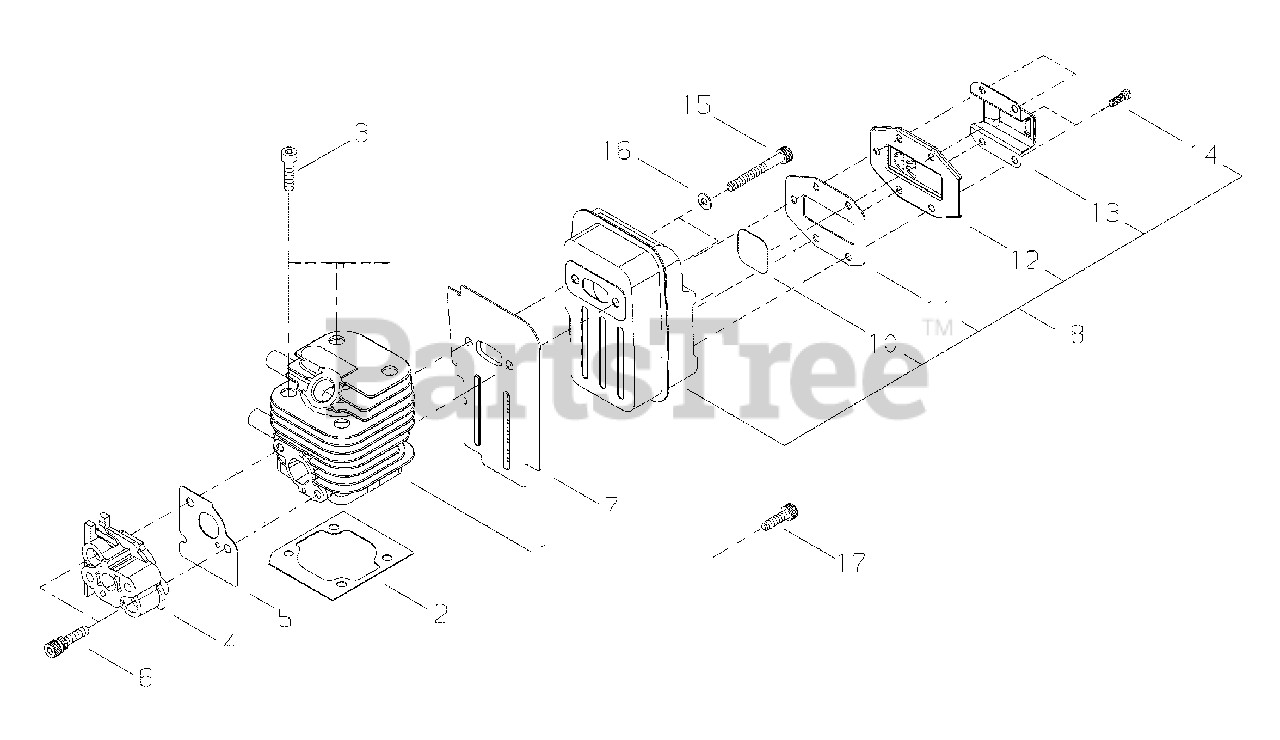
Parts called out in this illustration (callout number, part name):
1	CYLINDER
2	GASKET, CYLINDER
3	BOLT 5×16
4	INSULATOR
5	HEAT SHIELD, INTAKE
6	BOLT SS M5×30
7	HEAT SHIELD, EXHAUST
8	MUFFLER ASSY
10	SCREEN, SPARK ARRESTER
11	GASKET, EXHAUST
12	COVER, SPARK ARRESTER
13	OUTLET, EXHAUST
14	SCREW M4×8
15	BOLT M5×55
16	WASHER SS 5 MM
17	BOLT 5×12
